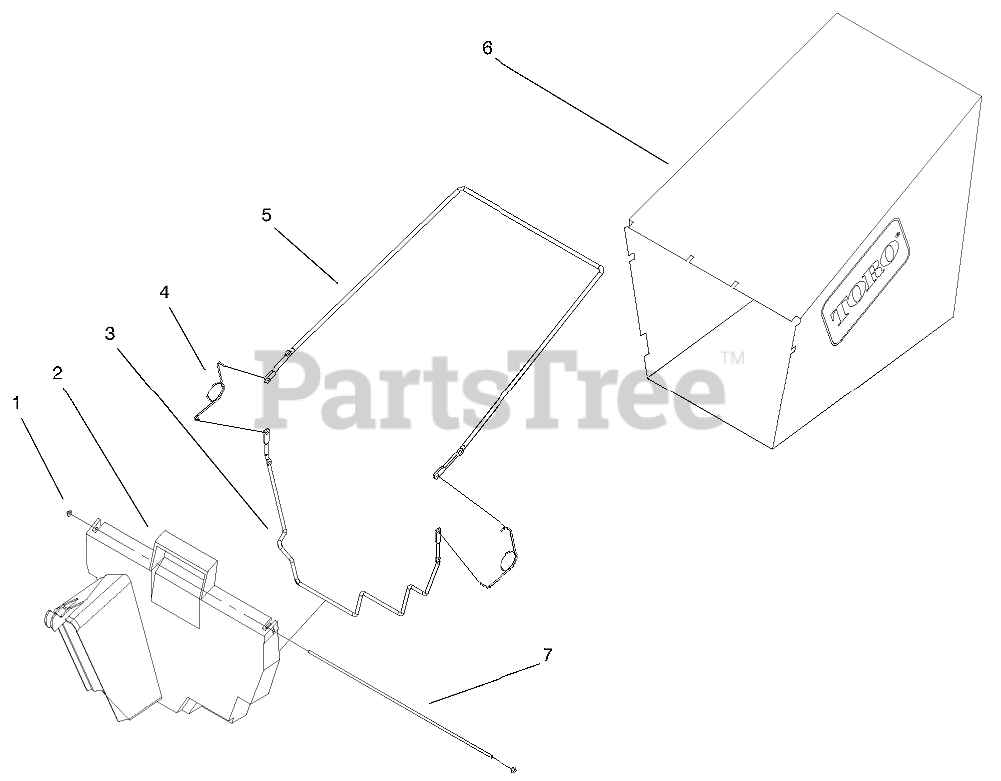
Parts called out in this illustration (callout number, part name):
1	Nut-Push (Only On: 20023)
2	Door-Bag (Only On: 20023)
3	Frame-Lower Bag (Only On: 20023)
4	Spring (Only On: 20023)
5	Frame-Upper Bag (Only On: 20023)
6	Bag-Grass (Only On: 20023)
7	Hinge-Bag Door (Only On: 20023)
